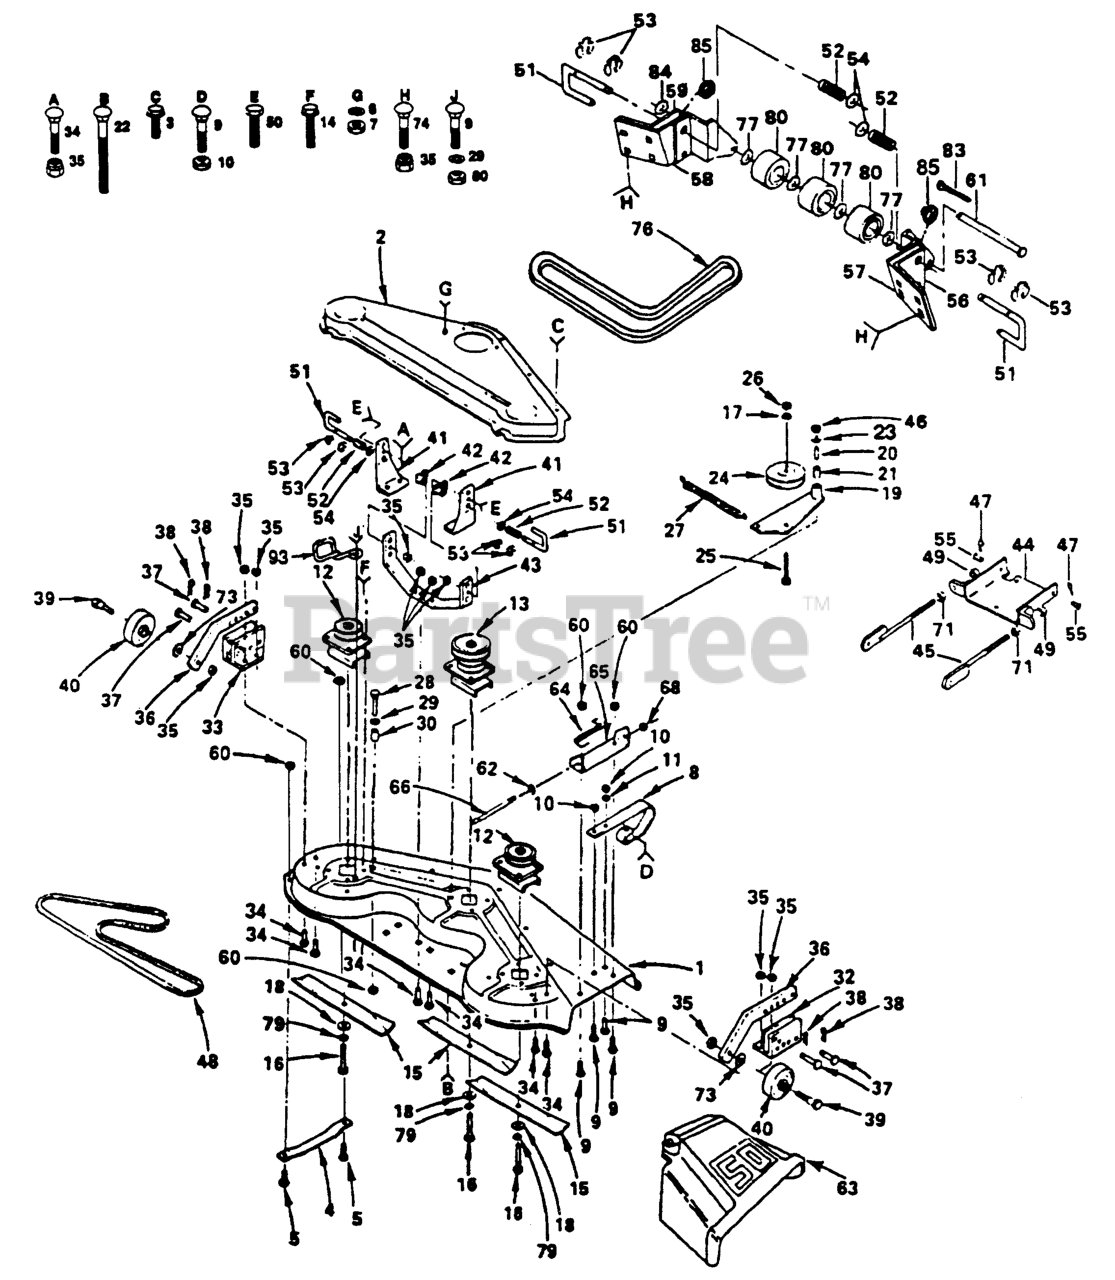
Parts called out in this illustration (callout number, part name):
1	HOUSING
2	CVR DRIVE DECK
3	Screw, Hex Washer Thr. Roll 5/16 18 x 1/2
4	RUNNER-LH M
5	BOLT.CARR.5/16-18X5/8.SHORT
6	WASHER.LOCK.HVY.HLCL.SPR.5/16
7	NUT
8	RUNNER T
9	RP BOLT 5/16-18 X3/4 ZN/YEL GR
11	WASHER
12	MANDREL ASM SEC 44/50
13	MANDREL, PRIMARY
14	SCREW
15	BLADE.50".STANDARD.LIFT
16	BOLT.3/8-24X1-1/2
17	WASHER, LOCK 3/8
18	WASHER
19	ARM ASSY GT
20	BEARING ASSY M
21	BEARING ASSY M
22	Bolt, Carriage 5/16-18 x 2-3/4
23	Washer 11/32 x 1-1/8 x 16 Gauge
24	IDLER-FLAT T
25	BOLT
26	NUT.HEX.3/8-16UNC
28	BOLT.5/16-18X1-1/4 FULL.THREAD
29	WASHER M
30	SPACER SPLIT LT
32	GUAGE WHL BRKT GT
33	GAUGE WHL BRKT GT
34	Bolt, Carriage 3/8-16 x 3/4
36	GUAGE WHL BAR GT
37	CLEVIS PIN T
38	RETAINER-SPRNG RB
39	BOLT, SHOULDER
40	WHEEL.GAUGE.BLK.4.93
41	SUSP BRKT GT
43	SUSP BRACE GT
45	BRACKET NLA
46	JAM NUT TI
47	SPRING RETAINER
49	NUT LTV
50	Bolt, Hex 3/8-16 x 1-3/8
51	RELEASE PIN GT
52	SPRING.COMPRESSION
54	WASHER GT
55	CLEVIS PIN GT
60	LOCKNUT
61	PIVOT PIN T
62	Washer 11/32 x 5/8 x 16 Gauge
63	SHIELD.DEFLECTOR.MOWER.50"BLK.
64	DEFLECTOR SPRG T
65	BRACKET, DEFLECTOR
66	ROD-HINGE T
68	NUT PUSH M
71	NUT.HEX.3/8-16UNC
73	Washer 17/32 x 15/16 x 12 Gauge
76	BELT-V.93.5.MOWER
77	WASHER T
79	LOCKWASHER
83	COTTER PIN
84	WASHER
93	BELT RETIANER
